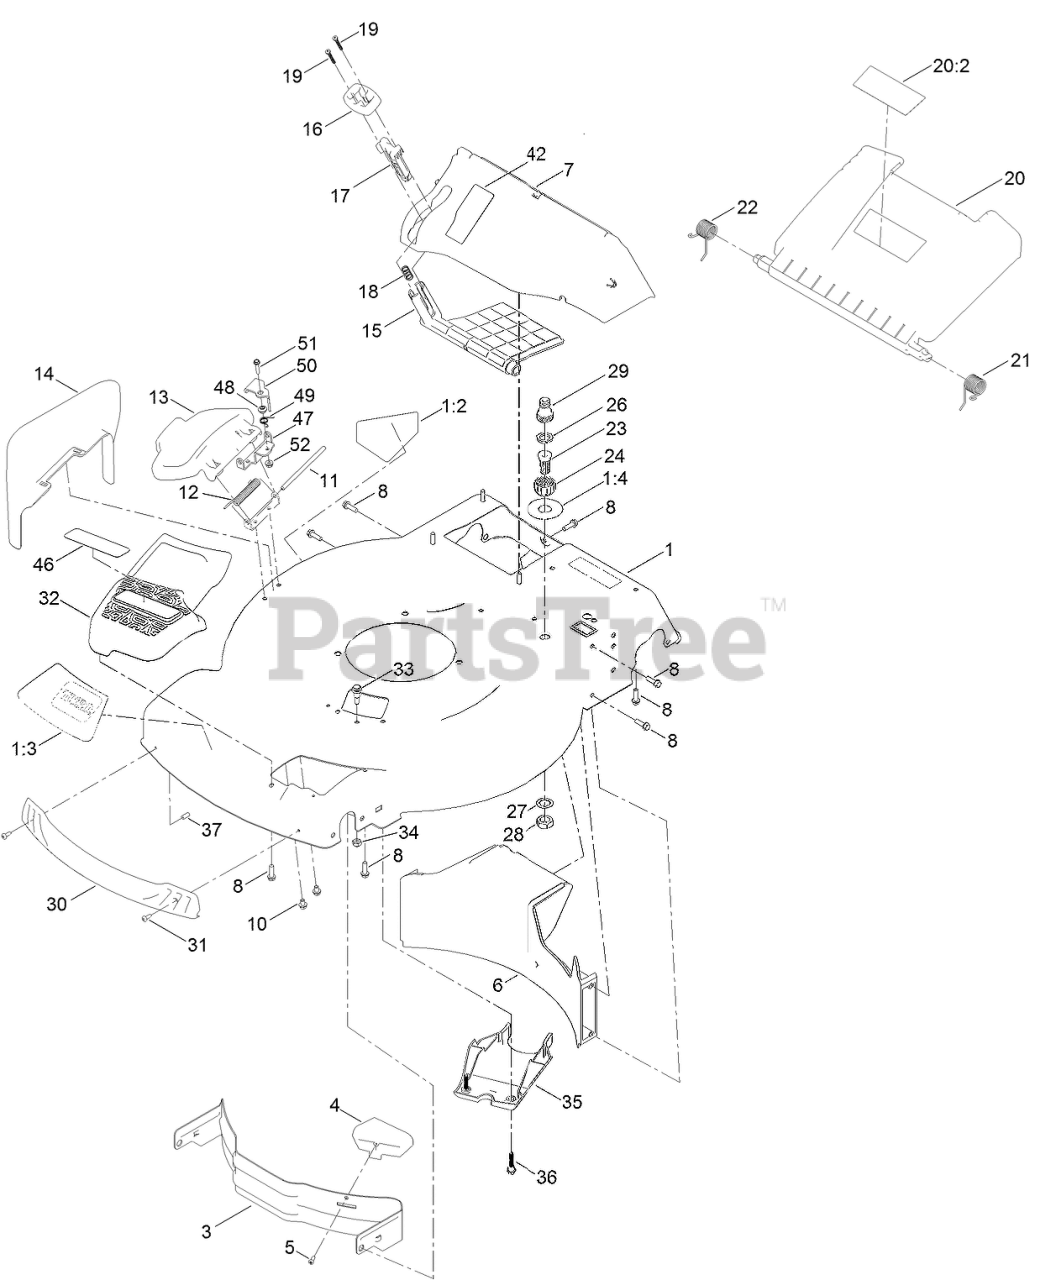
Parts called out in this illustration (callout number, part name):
1	HOUSING ASM
1:2	DECAL-DANGER
1:3	DECAL-DECK
1:4	DECAL-QUICK WASH
3	BAFFLE-FRONT
4	KICKER-FRONT
5	SCREW-PLASTIC, PPH
6	BAFFLE-REAR
7	CHUTE-RECYCLE
8	SCREW-PLASTITE, HWH
12	SPRING-TORSION
13	DEFLECTOR-DISCHARGE, SIDE
14	CHUTE-DISCHARGE, SIDE
15	DEFLECTOR-RECYCLE
16	KNOB-RECYCLE
17	LATCH-RECYCLE
18	SPRING-COMPRESSION
19	SCREW-PPH
20	REAR DOOR ASM
20:2	DECAL-WARNING
21	SPRING-TORSION
22	SPRING-TORSION
23	PORT-WASHOUT
24	COUPLING-HOSE, WASHOUT PORT
26	WASHER-SEAL, WASHOUT PORT
27	WASHER-LOCK, INT TOOTH
28	NUT-JAM
29	ADAPTER-CONNECT, QUICK
30	BUMPER
31	SCREW-FORMING, THREAD
32	COVER-BELT, FRONT
33	BOLT-SHOULDER
34	NUT-LOCK
35	COVER-BELT, FRONT
36	SCREW-SHOULDER, HHF
37	CAP-PLUG
46	DECAL-BELT COVER, POWEREVERSE
47	BRACKET-LOCKOUT
48	SPACER
49	SPRING-TORSION
50	LEVER-LOCKOUT
51	SCREW-HWH
52	NUT-HEX FLANGE
